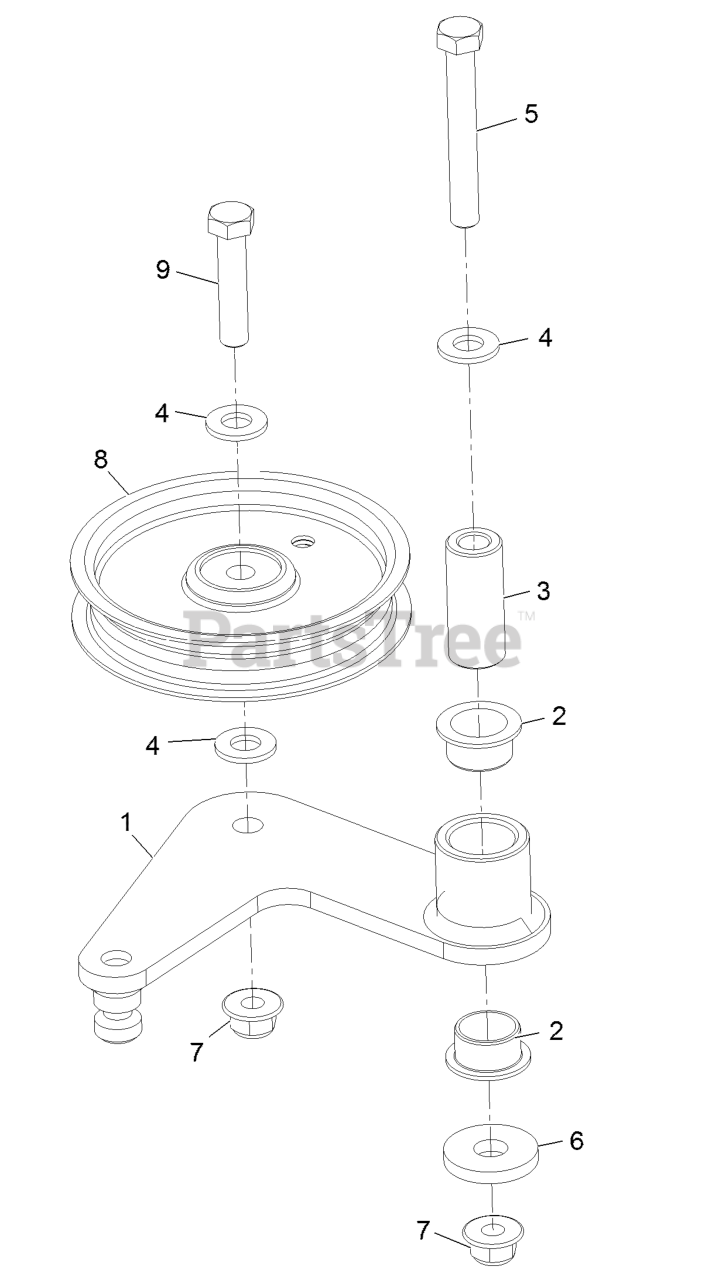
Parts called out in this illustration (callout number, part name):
1	Idler Arm ASM
2	Bushing-Flanged
3	Spacer, Pivot
4	Washer-3/8 SAE
5	Screw-HH 3/8-16 X 2 3/4
7	Nut-Nyloc 3/8-16 Flg
8	Pulley-Idler
9	Screw-HH 3/8-16 X 1 3/4
